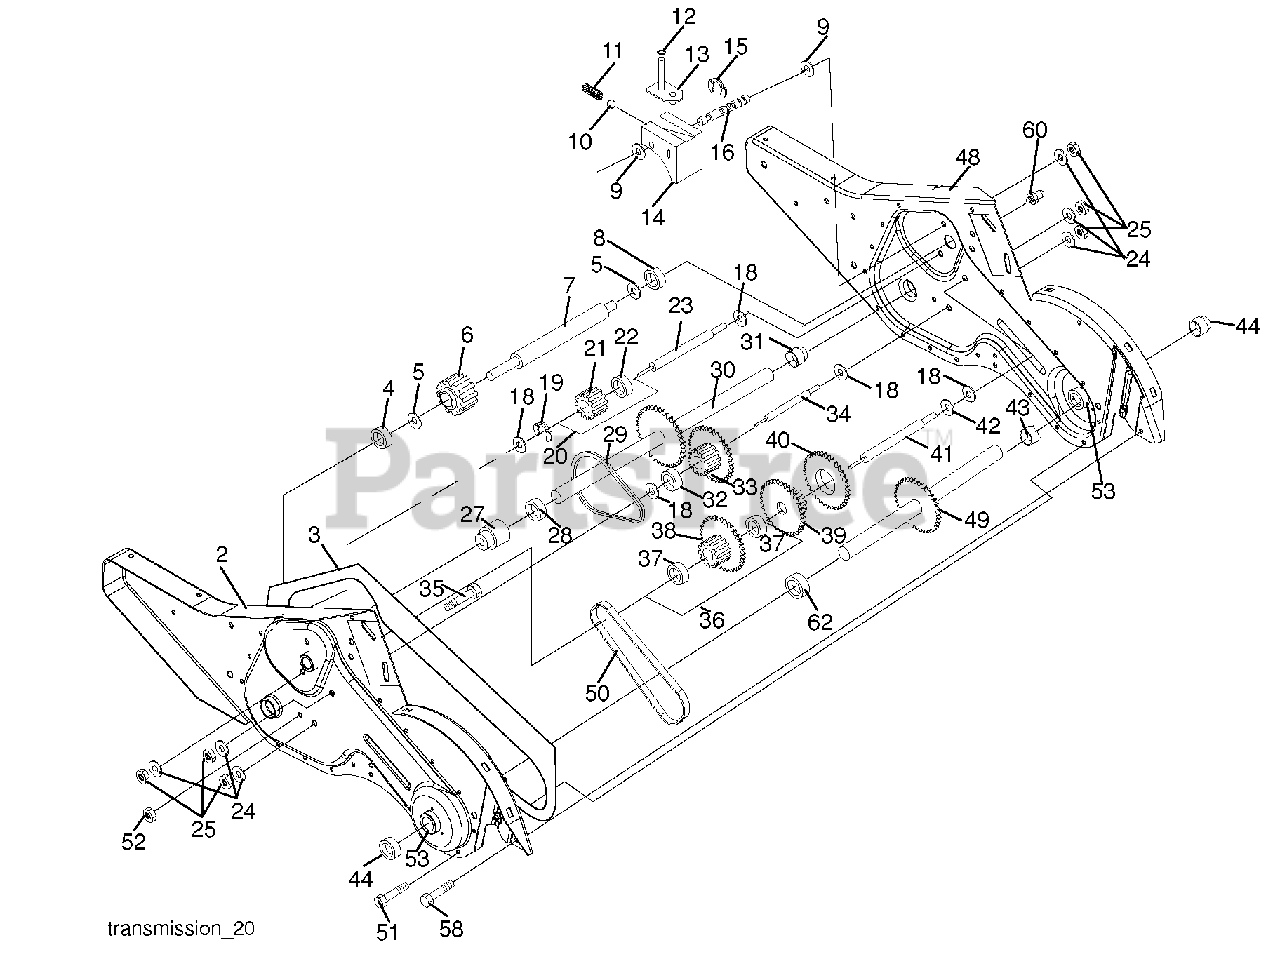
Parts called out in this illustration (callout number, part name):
1	Transmission Assembly
2	Gearcase, L.H. w/Bearing
3	Gasket, Gearcase
4	Bearing, Needle
5	Washer, Thrust 5/8 x 1.10 x 1/32
6	Pinion, Input
7	Shaft, Input
8	Bearing, Needle
9	Washer, Seal
10	Ball, Steel
11	Spring, Shift, Fork
13	Arm, Shift
14	Fork, Shift
15	Ring, Klip
16	Shaft, Shift
19	Ring, Klip
20	Gear, Assembly, Reverse Idler
21	Gear, Reverse Idler
22	Bearing, Needle
23	Shaft, Reverse Idler
24	Washer, Lock 7/16
25	Nut, Hex 7/16-20
27	Bearing, Shaft, Ground Drive L.H.
28	Spacer 0.765 x 1.125 x 1.23
29	Chain #35-50 Pitch
30	Ground Shaft Assembly
31	Bearing, Shaft, Ground Drive R.H.
32	Spacer 0.70 x 1.00 x 1.150
33	Sprocket and Gear Assembly
34	Shaft, Reduction (2nd)
35	Screw, Whiz, Lock 5/16-18 x 3-1/2
36	Sprocket Assembly w/Bearing
37	Bearing, Needle
38	Sprocket, Tine
39	Gear, Cluster, Red 1st & 2nd
40	Gear, Reverse
41	Shaft, Reduction (1st)
42	Washer, Thrust
43	Spacer 1.01 x 1.75 x 0.760
44	Seal Asm, Oil
48	Gearcase, R.H. w/Bearing
49	Shaft, Tine
50	Chain, Roller #50-50 Pitch
51	Screw 1/4-20 x 1/2
52	Nut, Hex 5/16-18
53	Kit, Bearing
58	Bolt Shoulder 1/4-20 unc x .875
60	Fitting Grease
